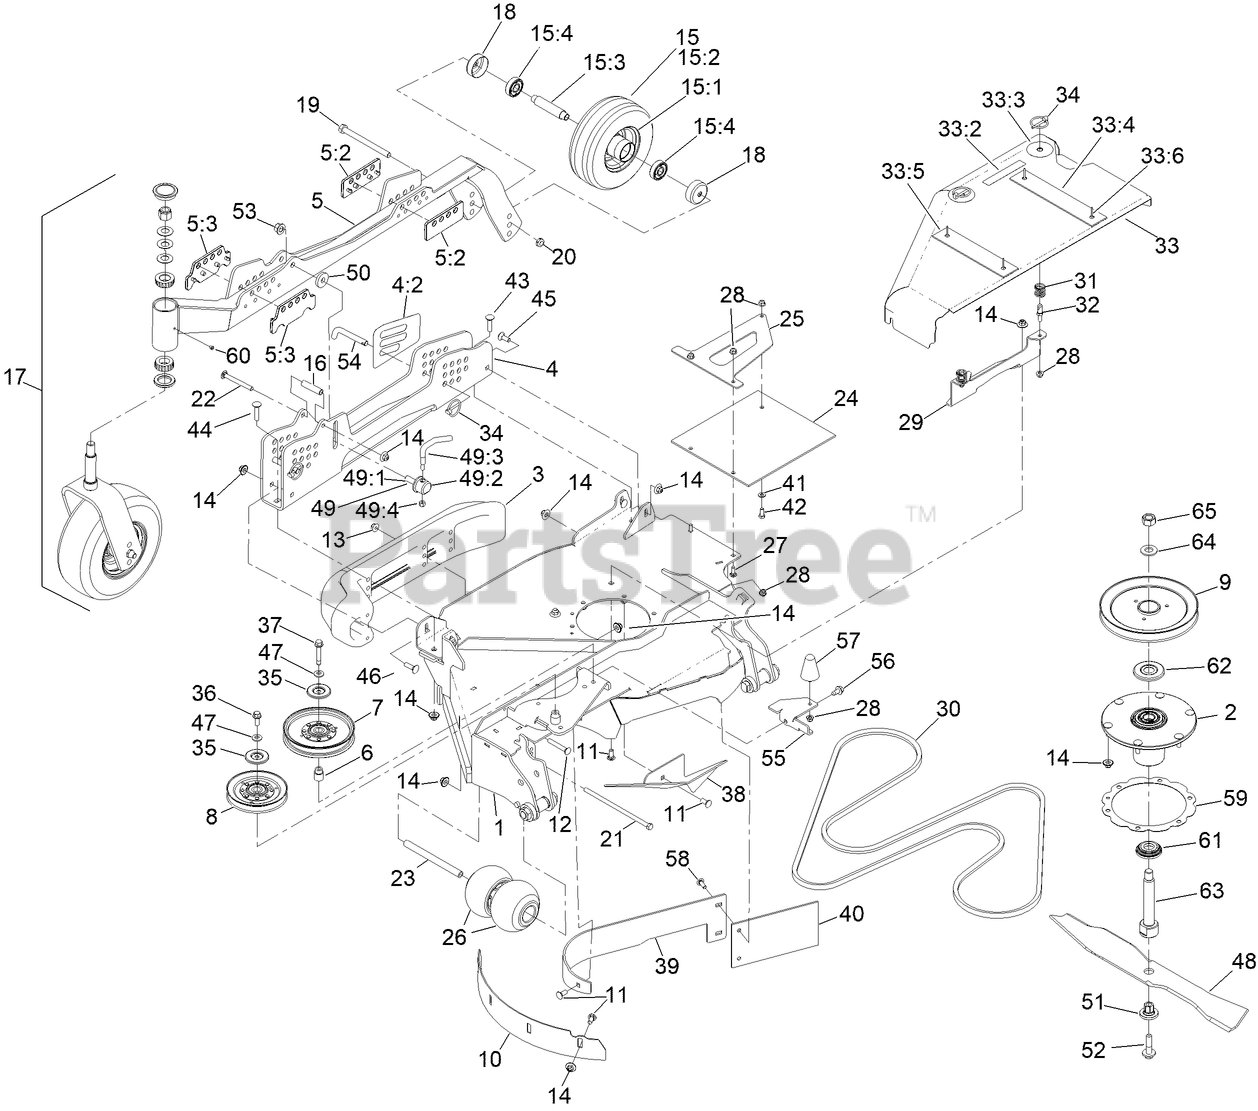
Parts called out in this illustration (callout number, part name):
1	ASM-DECK, RH WING [W/DECALS]
2	SPINDLE ASM
3	SKID-BUMPER, DECK
4	ASM-CHANNEL, HOC RH W/DECALS
4:2	DECAL-HEIGHT OF CUT, RH
5	ASM-RH GAUGE WHEEL ARM
5:2	PLATE-GUIDE, REAR
5:3	PLATE-GUIDE, FRONT
6	BUSHING-IDLER
7	IDLER-PULLEY
8	IDLER-V
9	SHEAVE-DRIVE, BLADE
10	BAFFLE-DEPTH, RH
11	BOLT-CARR
12	SCREW-CARR
13	NUT-HF, NI
14	NUT-FLANGE, NI
15	WHEEL AND TIRE ASM
15:1	WHEEL
15:3	AXLE-CASTER
15:4	BEARING
16	SPACER
17	CASTER WHEEL ASM
18	GUARD, SEAL
19	SCREW-HH
20	NUT-HEX
21	SCREW-HH
22	SCREW-CARR
23	SPACER-WHEEL
24	GUARD-TIRE
25	SUPPORT-FLAP, RH
26	ROLLER-SCALP, ANTI
27	SCREW-CARR
28	NUT-HF, NI
29	BRACKET-SHIELD MOUNT, OUTER
30	BELT-V
31	SPRING
32	PIN, SPRING
33	RH WING SHIELD ASM
33:2	DECAL-NO STEP
33:3	DECAL-SCRATCH COVER
33:5	PLATE-FRONT
33:6	RIVET-POP
34	PIN-LYNCH
35	SHIELD-DUST
36	SCREW-HHF
37	SCREW-HHF W/ PATCH
38	BAFFLE-DEFLECT, RH
39	BAFFLE-DOGLEG, RH
40	FLAP-RUBBER
41	WASHER-PLAIN
42	SCREW-HH
43	SCREW-CARR
44	SCREW-CARR
45	BOLT-CARR
46	BOLT-CARR
47	WASHER-BELLEVILLE
48	BLADE-24.50 MULCH
49	LEVER ASM
49:1	SCREW-LOCK
49:2	CAP-LOCK
49:4	NUT-LOCK, NI
50	WASHER
51	BUSHING-HEX
52	SCREW-SEMS
53	NUT-LOCK
54	PIN-HOC
55	BRACKET-COVER RETAINER
56	SCREW-HWH
57	BUMPER-RUBBER
58	SCREW-CARR
59	RING-SPACER, HOUSING
61	GUARD-BOTTOM
62	GUARD-BEARING, TOP
63	SHAFT-SPINDLE
64	WASHER
65	NUT-HEX
